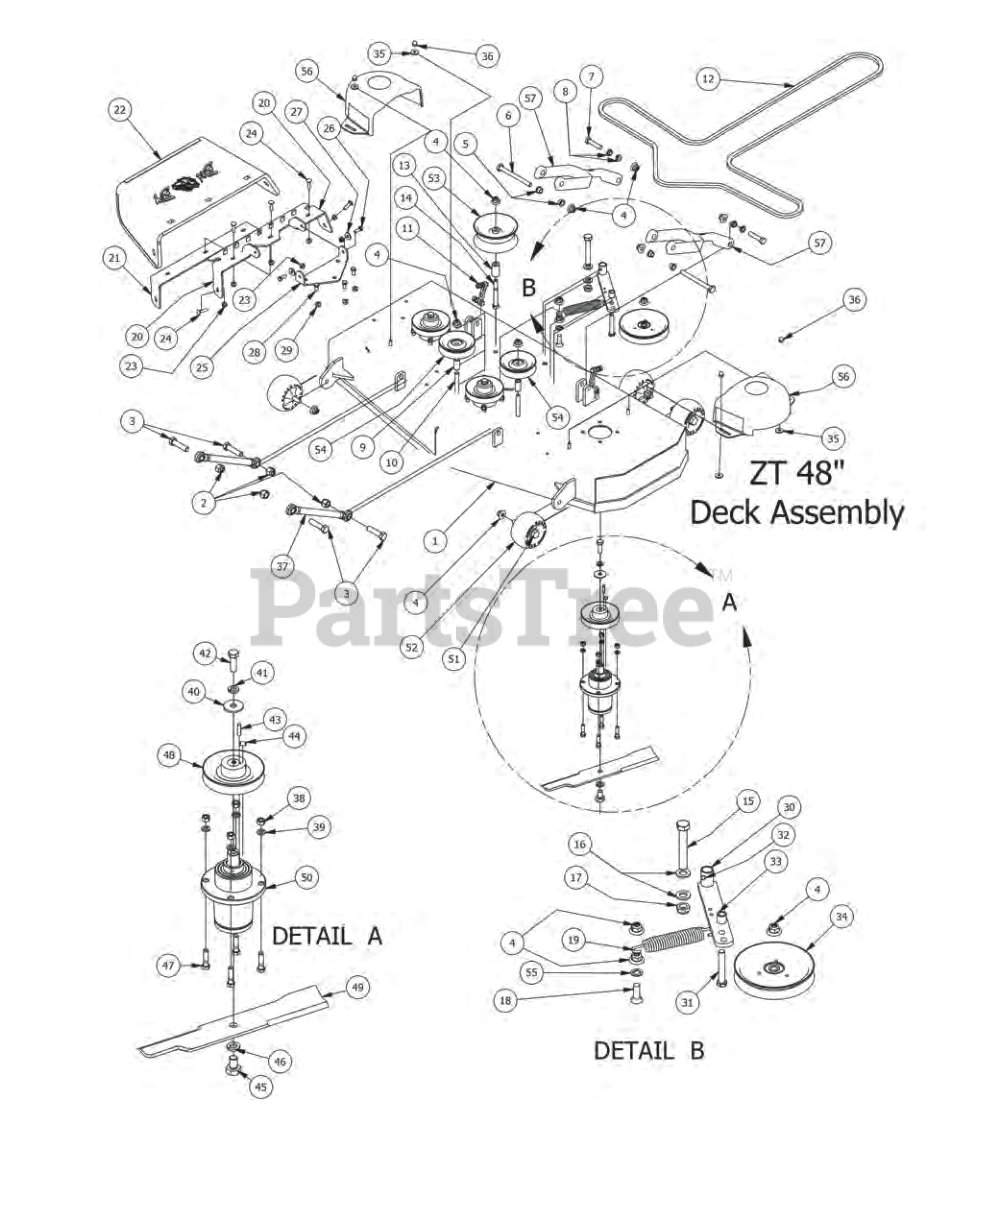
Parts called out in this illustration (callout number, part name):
1	2014 ZT/CZT 48" Deck
2	5/8 Std NC Nylock Nut
3	5/8" x 2 1/2" Gr5 Hex Bolt (Coarse)
4	1/2-13 Nylon Flange Nut-Orange
5	Flange Bushing For Deck Arm upper
6	1/2" x 5 1/2" Bolt
7	1/2-13X 2-1/4 GR Hex Bolts
8	Flange for Lower Deck Arm
9	.502 ID X.75 OD X 1,500 Leng
10	1/2 x 3 1/2 Flange Bolt Grade 8
11	Chain assembly
12	50" Deck Belt
13	13/4" Pulley Spacer
14	1/2" x 4" Bolt (Grade 8)
15	5/8" x 4" Hex Bolt
16	.635 ID Plastic Washer
17	5/8-11 Nylon Insert Jam Half Nut
18	1/2 x 1-1/2 Carriage Bolt
19	2009 Deck/Pump Idler Spring
20	Upper Hanger
21	Discharge Lower Chute Bracket
22	Rubber Discharge Chute
23	5/16" Nylon Flange Nut
24	5/16" x 1 1/4" Carriage Bolt
25	Discharge Chute Hanger (deck mounted)
26	5/16" x 1" Bolt
27	.360 ID Plastic Washer
28	3/8" x 3/4" Hex Bolt
29	3/8" Flange Nut
30	Deck Idler
31	1/2-13 x GR 5 Hex Bolt Zinc
32	1/4" Press in Grease Fitting
33	3/4 OD x 1/2 ID x 3\4 Length
34	5-3/4 Idler Pulley
35	360 ID Plastic Washer-Black
36	Acom nut-pulley Cover
37	Turnbuckle (Top Link)
38	3/8" Hex Nut
39	3/8" Lock Washer
40	1/2 Belleville Washer
41	1/2" Lock Washer
42	1/2"-20 x 1 1/2 - Grade 5 Fine Thread Bolt
43	1/4" x 1" Key
44	5/16 Set Screw
45	5/8" x 1 1/2" Gr8 Hex Bolt (Fine)
46	5/8" Lock Washer
47	3/8" x 1 1/2" Hex Bolt
48	5" Deck Pulley
49	48" High Lift Fusion Blade
50	ZT/CZT SPINDLE ASSEMBLY
51	Deck Wheel Bolt
52	Anti-Scalp Rollers
53	5 3/4" Deck Idler Pulley
54	4 3/4" Idler Pulley
55	517 Square Hole Round Washer
56	Pulley Cover
57	Deck Arm Assembly
